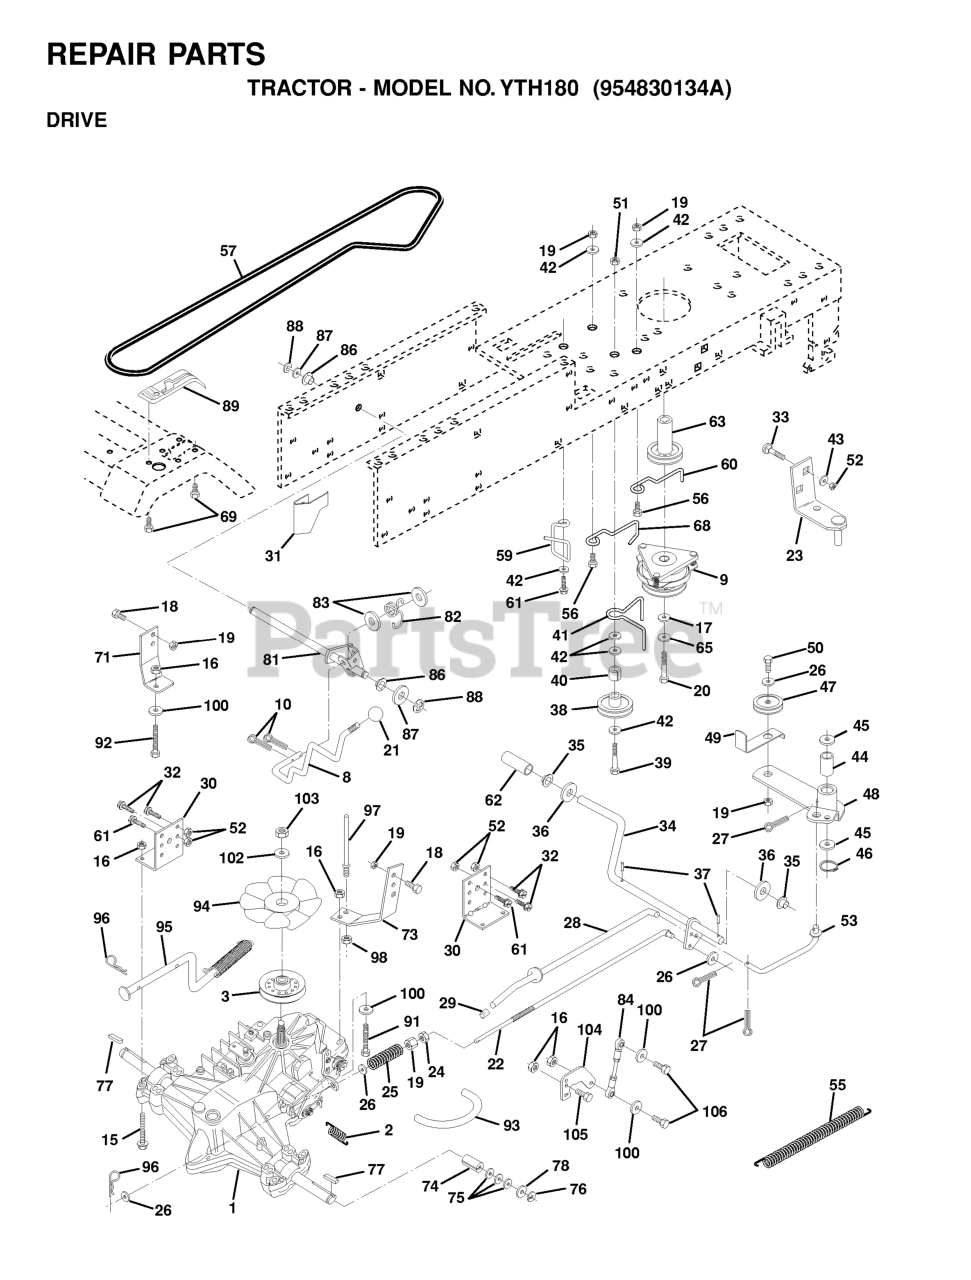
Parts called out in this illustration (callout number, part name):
1	TRANSAXLE ASSEMBLY
2	SPRING BRAKE
3	PULLEY, TRANSAXLE
9	CLUTCH.ELECT.CVX.105 FT/LB.
10	PIN COTTER
15	BOLT HEX 5/16-18 GR 5
16	NUT.71038.31-18.HEX.NYLOCK
19	NUT
20	BOLT
21	KNOB.DELUXE.(PISTOL.GRIP).BLAC
22	ROD BRAKE HYDRO
23	BRACKET ASM MTG
24	NUT
25	SPRING ROD LT
26	WASHER
27	COTTER PIN
28	ROD BRAKE PARK LT
29	PLUNGER CAP
30	BRACKET TRANSAXLE
31	KEEPER BELT LH
32	BOLT
33	RP BOLT 5/16-18 X3/4 ZN/YEL GR
34	SHAFT PEDAL FOOT
35	BEARING.NYLON
37	DRIVE PIN
38	PULLEY.IDLER.FLAT
41	BELT KEEPER LT NLA
42	WASHER
44	BEARING LT (2 2)
47	IDLER PULLEY
49	RETAIN BELT
50	BOLT
52	LOCKNUT
53	LINK, CLUTCH LT
55	SPRING, RETURN LT
57	DRIVE BELT, LTH & YTH TRACTORS
59	KEEPER CENTER SPAN
60	KEEPER,BLT ENG LT
61	SCREW
62	COVER, PEDAL (1 2)
63	PULLEY CLU ELEC
65	LOCKWASHER
68	KEEPER BELT ENGLH
69	SCREW.HI-LO.CONSOLE
71	STRAP LH TORQUE
73	STRAP RH TORQUE
74	SPACER SPLIT
77	SQUARE KEY
81	SHAFT ASSY
82	SPRING,TORSION
83	WASHER
84	ROD.TIE.BALL.4.75
86	BUSHING.STEERING.ROD LTB-WSL
89	CONSOLE HYDRO LT
91	BOLT.FIN HEX 5/16-18UNC X2 1/4
92	HEX BOLT
93	LINE FUEL HYD 4"
94	FAN 7" HYDRO
95	CONTROL ARM, BYPASS HYDRO
96	RETAINER M
97	KEEPER BELT RH
100	WASHER M
103	NUT.HEX.1/2-20
104	CONTROL ARM
106	BOLT.5/16-18X1-1/4 FULL.THREAD
